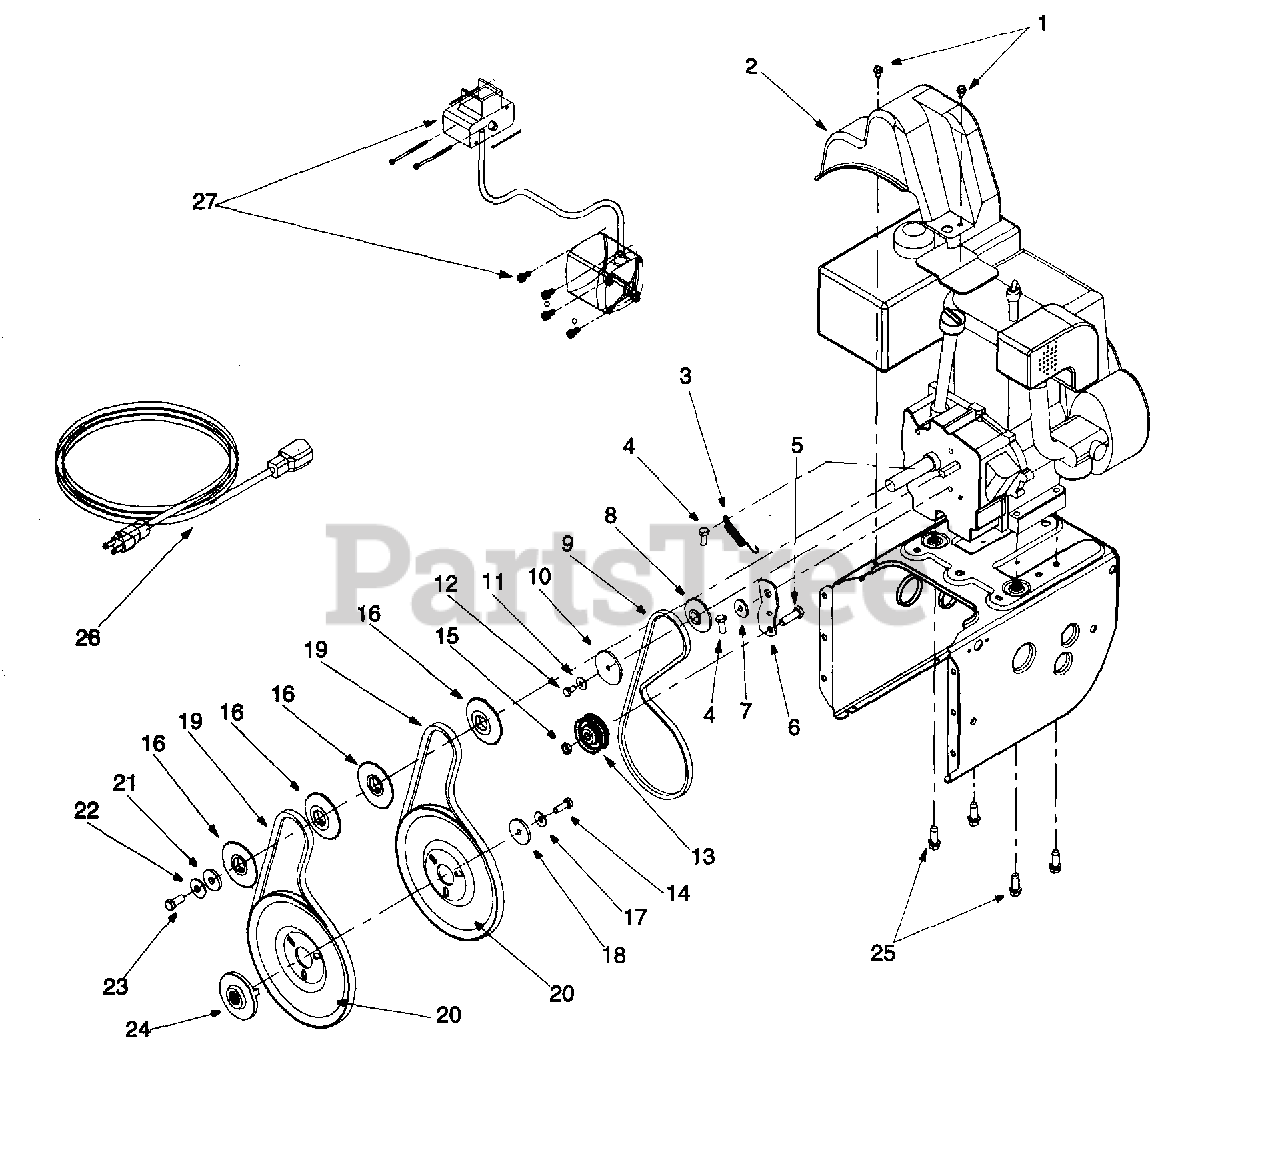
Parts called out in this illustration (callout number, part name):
1	Hex Washer Screw 1/4-20 x .50
2	Belt Cover
3	Extension Spring
4	Hex Screw 5/16-24 x .75
5	Hex Cap Screw 3/8-16 x 1.25
8	Pulley Half
9	V-Belt
10	Pulley Half
11	Bell Washer
12	Hex Cap Screw 1/4-28 x .50
13	Flat Idler
14	Lock Hex Cap Screw 5/16-24
15	Lock Jam Nut 3/8-16
16	Pulley Half
17	Bell Washer
18	Flat Washer
19	Belt
20	Auger Pulley
21	Flat Washer 3/8 x 1.25 OD
22	Bell Washer
23	Hex Cap Screw 3/8-24
24	Adapter Pulley
25	Hex Screw 3/8-16 x 1.0
26	Extension Cord
27	Electric Start
